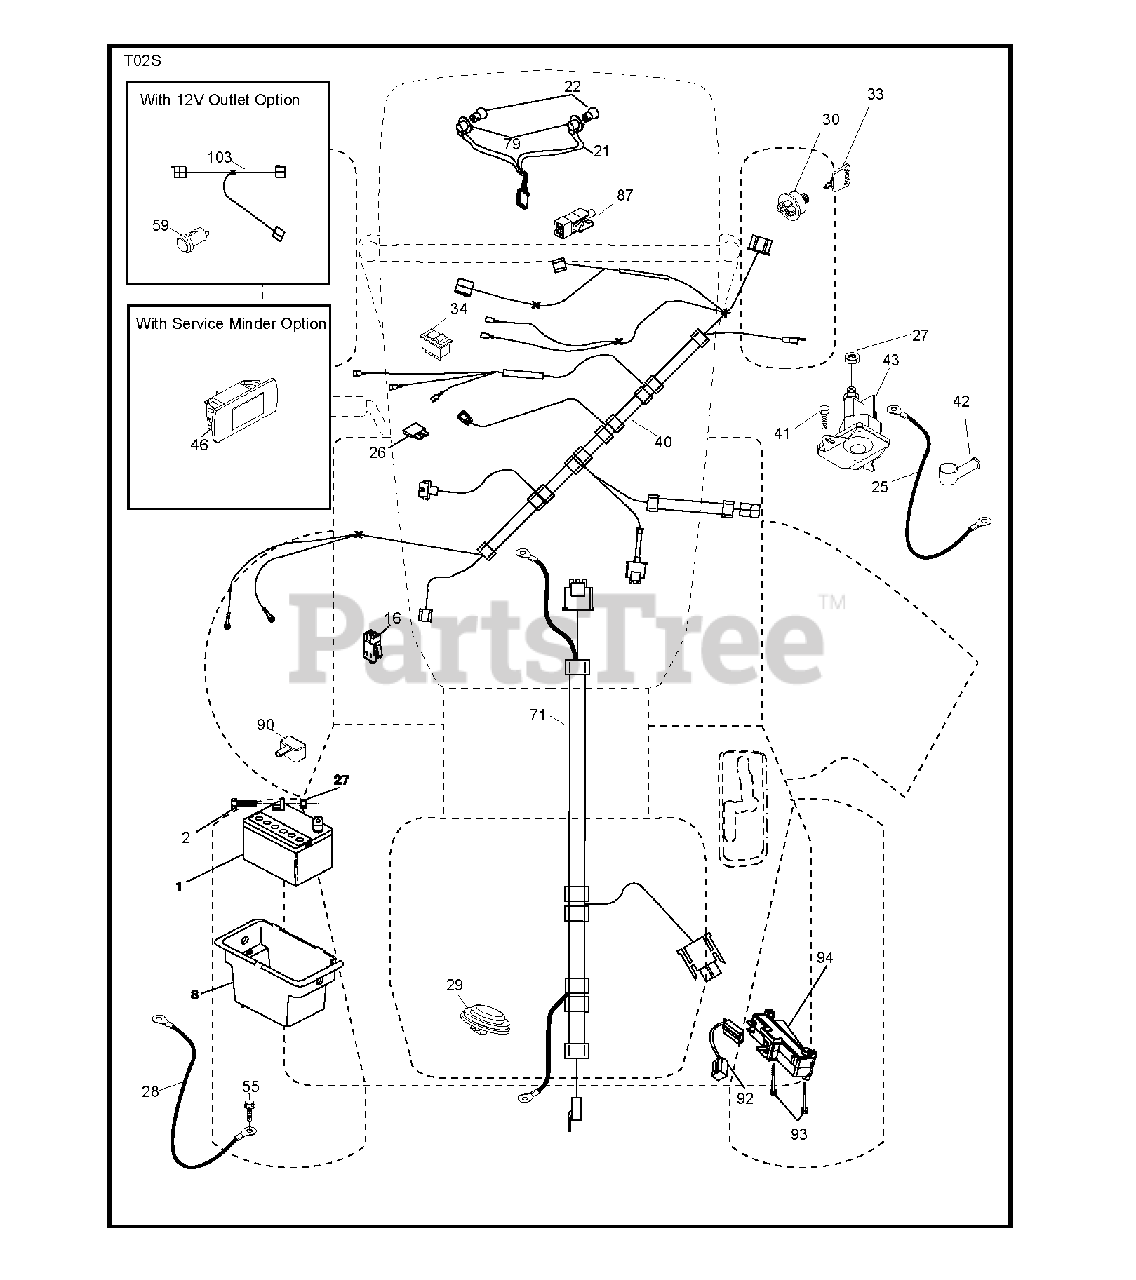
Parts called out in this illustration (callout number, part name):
1	REPL BY 532 12 38-99
8	BOX.BATTERY.MNT.REAR.L
16	SWITCH INTERLOOK PUSH-IN
21	HARNESS.LIGHT W/4152J BULBS
22	LIGHTBULB
25	CABLE.STARTER.6GA.BL/RED.14.
26	FUSE 20AMP
27	NUT
28	CABLE.BLACK.18"REAR.BA
29	SWITCH.SEAT.DELTA.OPC.
30	SWITCH.IGN.DELTA.W.LGH.ROS
33	KEY.CHAIN.BLISTER.PACK.GEN.INT
34	SWITCH LT
40	HARNESS IGN. DASH
41	SCREW
42	TERMINAL COVER
43	SOLENOID.W/BRASS.PLUNG
55	SCREW 5/16"
71	HARNESS.IGN.CHASS.TEX.REAR.BAT
79	BULB HOLDER ASM.
87	SWITCH.INTRLCK.CLUTCH.
90	COVER, TERMINAL BATTERY
92	HARNESS.PIGTAIL.CONSLE
93	SCREW.PLASTITE
94	MODULE.REVERSE.ROS
